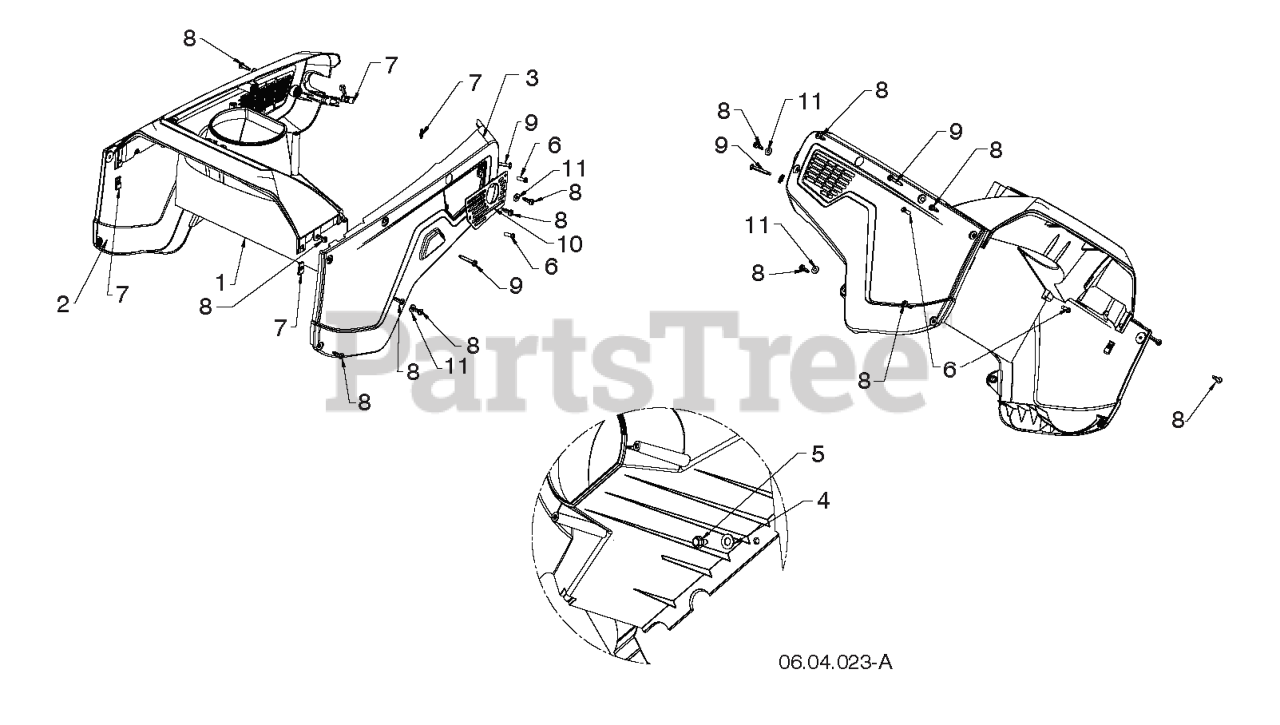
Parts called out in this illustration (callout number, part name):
1	AUGER.PLENUM.SINGLE.STAGE.GREY
2	COVER NON-DRIVE SIDE HUSQ ST1
3	COVER.DRIVE.SIDE.HUSQ.GY.ST111
4	WASHER
5	BOLT.HEX.HD.WASHER.5/16-18X.75
6	SCREW.HX.13X.750
8	SCREW.PAN.HD.TORX.1/4-20X.750
9	SCREW.1/4-20.PAN.HEAD.TORX.
10	PLATE.EXHAUST.SINGLE.STAGE.SNO
11	WASHER
